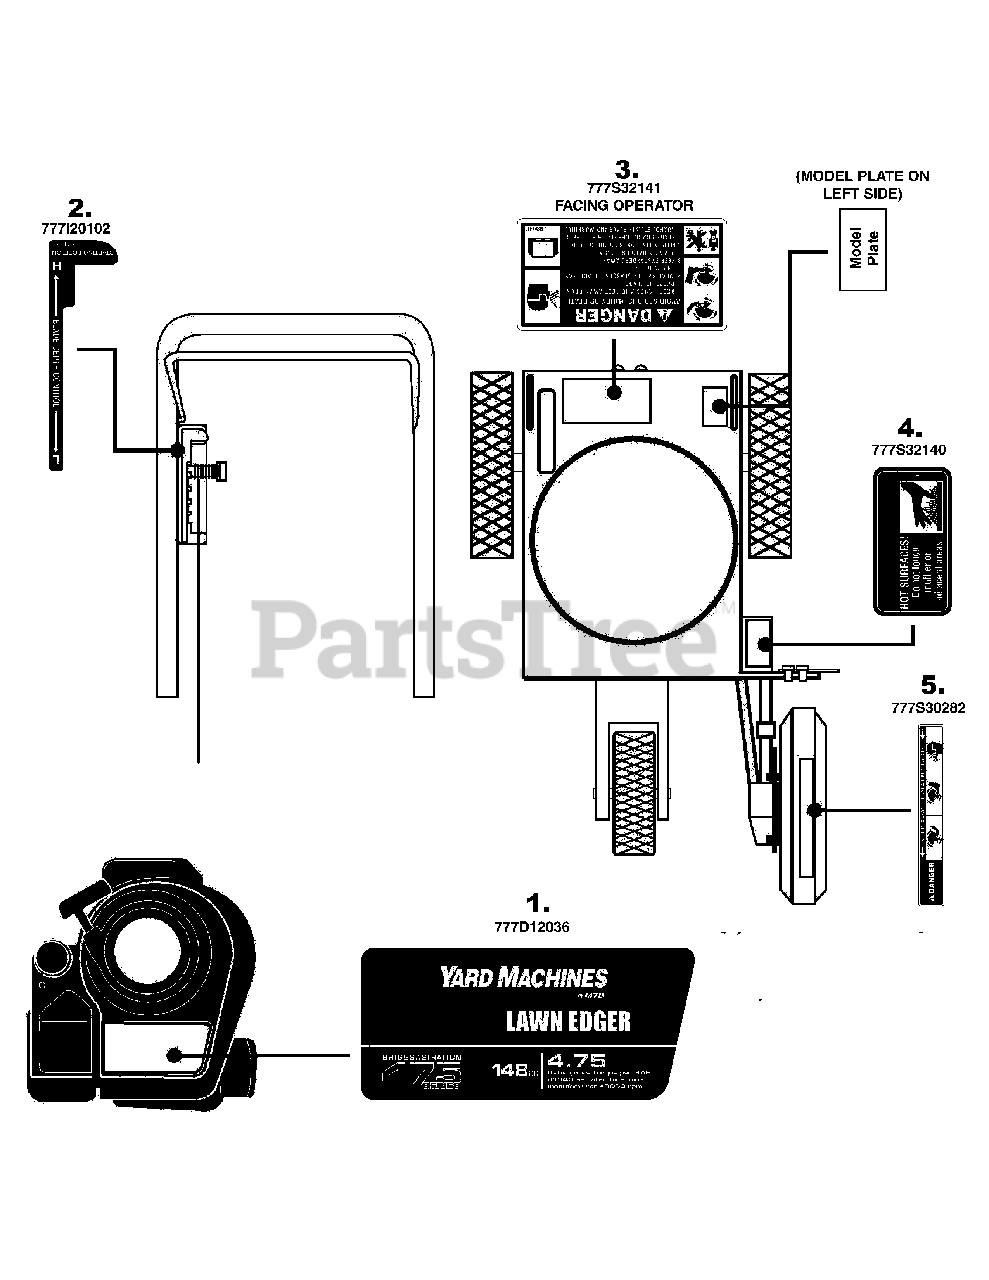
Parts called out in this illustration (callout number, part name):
1	LABEL-EDGER SHROUD YARD MACHINE
2	LABEL DEPTH CNTRL
3	LABEL-FRAME REAR
4	LABEL-MUFFLER
5	LABEL-BLADE COVER
